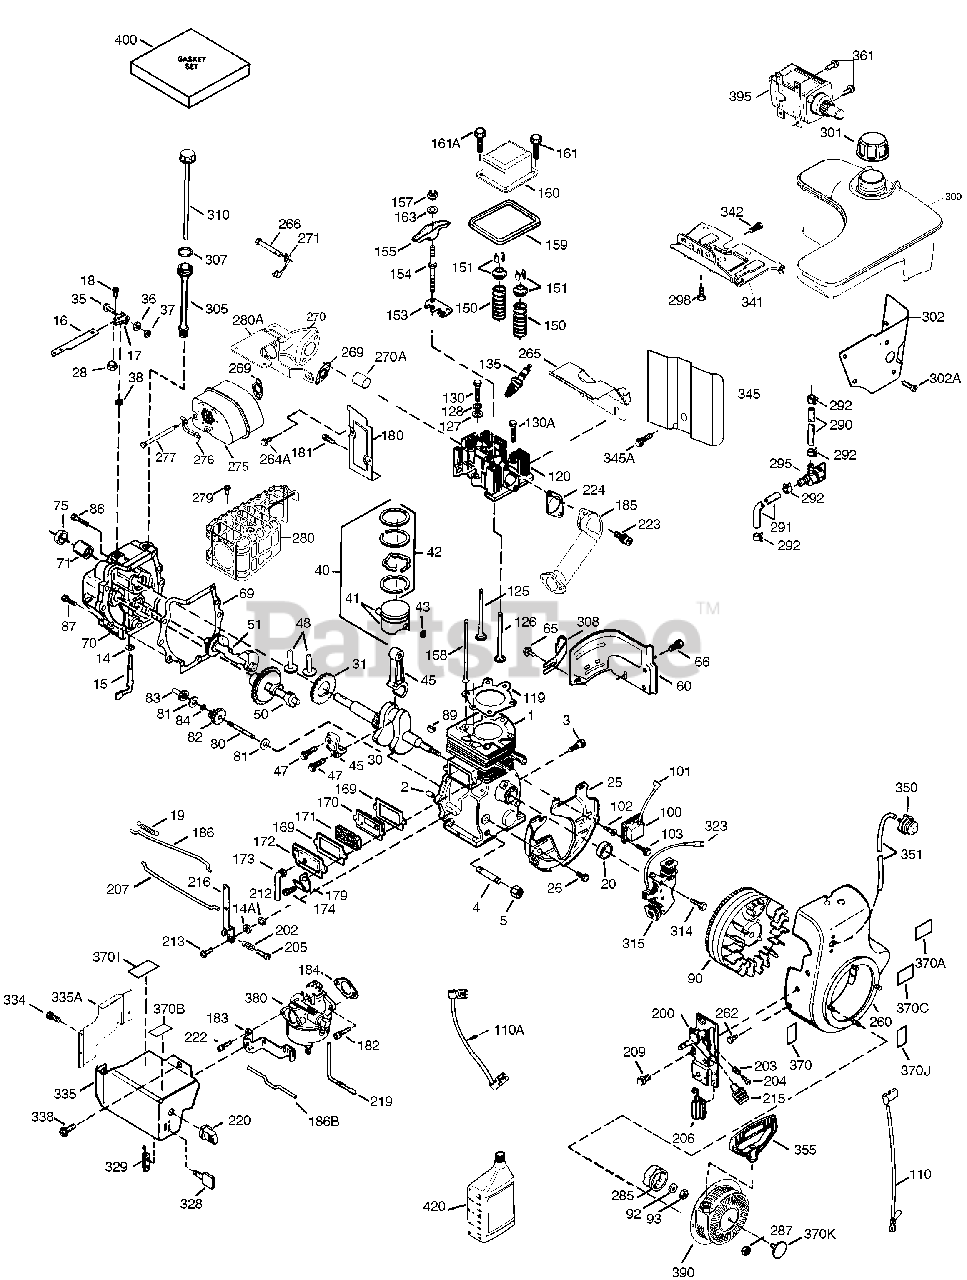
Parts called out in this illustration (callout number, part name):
1	"Cylinder (Incl. 2, 20, 72 & 80)
2	Dowel Pin
3	Screw, 1/4-20 x 1/2"
4	Oil Drain Extension
5	Extension Cap
14	Flat Washer
15	Governor Rod (Incl. 14 & 38)
16	Governor Lever
17	Governor Lever Clamp
18	Screw, Torx T-15, 8-32 x 3/8"
19	Extension Spring
20	Oil Seal
25	Blower Housing Baffle
26	Screw, 1/4-20 x 5/8"
28	Lock Nut, 8-32
30	Crankshaft
31	Counterbalance Gear
35	Screw, 10-32 x 3/4"
36	Lock Washer #8
37	Lock Nut, 10-32
38	Retaining Ring
40	Piston, Pin & Ring Set (Std) (Incl. 4 1, 42 & 43)
40	Piston, Pin & Ring Set (.010" OS) (In cl. 41, 42 & 43)
40	Piston, Pin & Ring Set (.020" OS) (In cl. 41, 42 & 43)
41	Piston & Pin Assembly (Std) (Incl. 43 )
41	Piston & Pin Ass'y. (.010" OS) (Incl. 43)
41	Piston & Pin Ass'y. (.020" OS) (Incl. 43)
42	Ring Set (Std.) (3-5/16")
42	Ring Set (.010" OS)
42	Ring Set (.020" OS)
43	Piston Pin Retaining Ring
45	Connecting Rod Ass'y (Incl. 47)
47	Connecting Rod Bolt
48	Valve Lifter
50	Camshaft (MCR)
51	Counterbalance Weight
60	Blower Housing Extension
62	Screw, 8-32 x 3/8"
65	Screw, 10-24 x 9/16"
69	* Cylinder Cover Gasket
70	Cylinder Cover (Incl. 14, 15, 38, 71 & 75)
71	Crankshaft Bushing
80	Governor Shaft
81	Washer
82	Governor Gear Assembly
83	Governor Spool
84	Retaining Ring
86	Screw, 1/4-20 x 1-3/16"
87	Screw, 1/4-20 x 1-11/16"
89	Flywheel Key
90	Flywheel (W/Ring Gear)
92	Lock Washer
93	Flywheel Nut
100	Solid State Ignition
101	Spark Plug Cover
102	Solid State Mounting Stud
103	Screw, Torx T-15, 10-24 x 15/16"
110	Ground Wire
110A	Ground Wire - Green, 5.5''
119	* Cylinder Head Gasket
120	Cyinder Head
124	Screw, 1/4-20 x 5/8"
125	Exhaust Valve (Std.)
125	Exhaust Valve (1/32" OS)
126	Intake Valve (Std.)
126	Intake Valve (1/32" OS)
128	Belleville Washer
130	Screw, 5/16-18 x 2-1/2"
135	Resistor Spark Plug (RN4C) also avail able in Packaged Part #740069
150	Valve Spring
151	Valve Spring Keeper
153	Push Rod Guide
154	Rocker Arm Stud
155	Rocker Arm
157	Jam Nut
158	Push Rod
159	* Rocker Arm Cover Gasket
160	Rocker Arm Housing
161	Screw, T-30, 1/4-20 x 1/2"
163	Lock Washer
169	* Valve Cover Gasket
170	Breather Body
171	Breather Element
172	Valve Cover
173	Breather Tube
174	Screw, 10-24 x 1/2"
178	Nut & Lock Washer 1/4-28
179	Retainer Clip
180	Blower Housing Extension
183	Choke Bracket
184	* Carburetor To Intake Pipe Gasket
185	Intake Pipe
186	Governor Link
186B	Choke Spring
200	Manual Control Bracket (Incl. 203, 20 4 & 206)
203	Compression Spring
204	Screw, Torx T-10, 6-32 x 41/64"
204	Screw, Torx T-10, 5-40 x 7/16"
206	Terminal
207	Throttle Link
212	Bushing
213	Screw, 10-32 x 5/8"
215	Control Knob
216	R.P.M. Adjusting Lever
219	Choke Rod
220	Control Knob
222	Screw, 10-32 x 1/2"
223	Screw, Torx T-30, 5/16-18 x 7/8"
224	* Intake Pipe Gasket
260	Blower Housing
262	Screw, T-40, 5/16-24 x 21/32"
265	Cylinder Head Cover
266	Screw, 5/16-18 x 1-1/4"
266	Screw, 5/16-18 x 1-9/32"
269	* Exhaust Gasket
270	Manifold
270A	Exhaust Port Liner
271	Locking Plate (Manifold)
275	Muffler
276	Locking Plate
276A	Locking Plate
277A	Screw, 5/16-18 x 4-1/2"
281	Starter Bubble Cover
285	Starter Cup
291	Fuel Line
292	Fuel Line Clamp
293A	Screw, 1/4-20 x 27/32"
298	Screw, 1/4-15 x 3/4"
300	Fuel Tank (Incl. 292 & 301)
301	Fuel Cap (Red)
305	Oil Fill Tube
307	"O" Ring
308	Fill Tube Clip
310	Dipstick
314	Screw, 1/4-20 x 3/4"
315	Alternator Coil (18 Watt) (Incl. 323)
323	Terminal
328	Ignition Key (also available in Packa ged Part #740077)
334	Screw, 8-32 x 5/16"
335	Carburetor Cover (Front)
335A	Carburetor Cover
336	Screw, 10-32 x 1/2"
338	Screw, 10-32 x 1/2"
341	Fuel Tank Bracket
342A	Screw, 5/16-18 x 7/8"
343	Key Switch Bracket
345	Heat Baffle
350	Primer Assembly (also available in Pa ckaged Part #740101)
351	Primer Line
355	Starter Handle (Mitten Grip) also ava ilable in Packaged Part #740053B
361	Screw, Torx T-30, 1/4-20 x 15/32"
370	Decal - Choke
370	Decal - Primer - International Symbol
370	-1
370	Decal - Tecumseh Logo for Top of Reco il Starter
370I	Warning Decal (Bilingual)
370J	Speed Control Decal
380	Carburetor (Incl. 184)
390	Rewind Starter NOTE: This Engine cou ld hav e been built with 590733 start er.
400	Gasket Set (Incl. items marked PK in notes) Incl. part #'s 27896A (2),332 63 (1),33515A (1),35317 (1),35683 (1) ,35762 (2),35952 (1), 36333 (1),36352 (1),36358 (1),36832 (1),36930 (1 ),3 6932 (1),36942 (1)
900	Replacement Engine None
900	Rep. Short Block 758215, order from 7 1-999
999	Winter Maintenance Kit incl. 5W30 Oil , Spark Plug, Key & Ultra-Fresh
999	Winter Maintenance Kit (incl. 0W30 Sy nthetic Oil, Spark Plug, Key & Ultra- Fresh)
